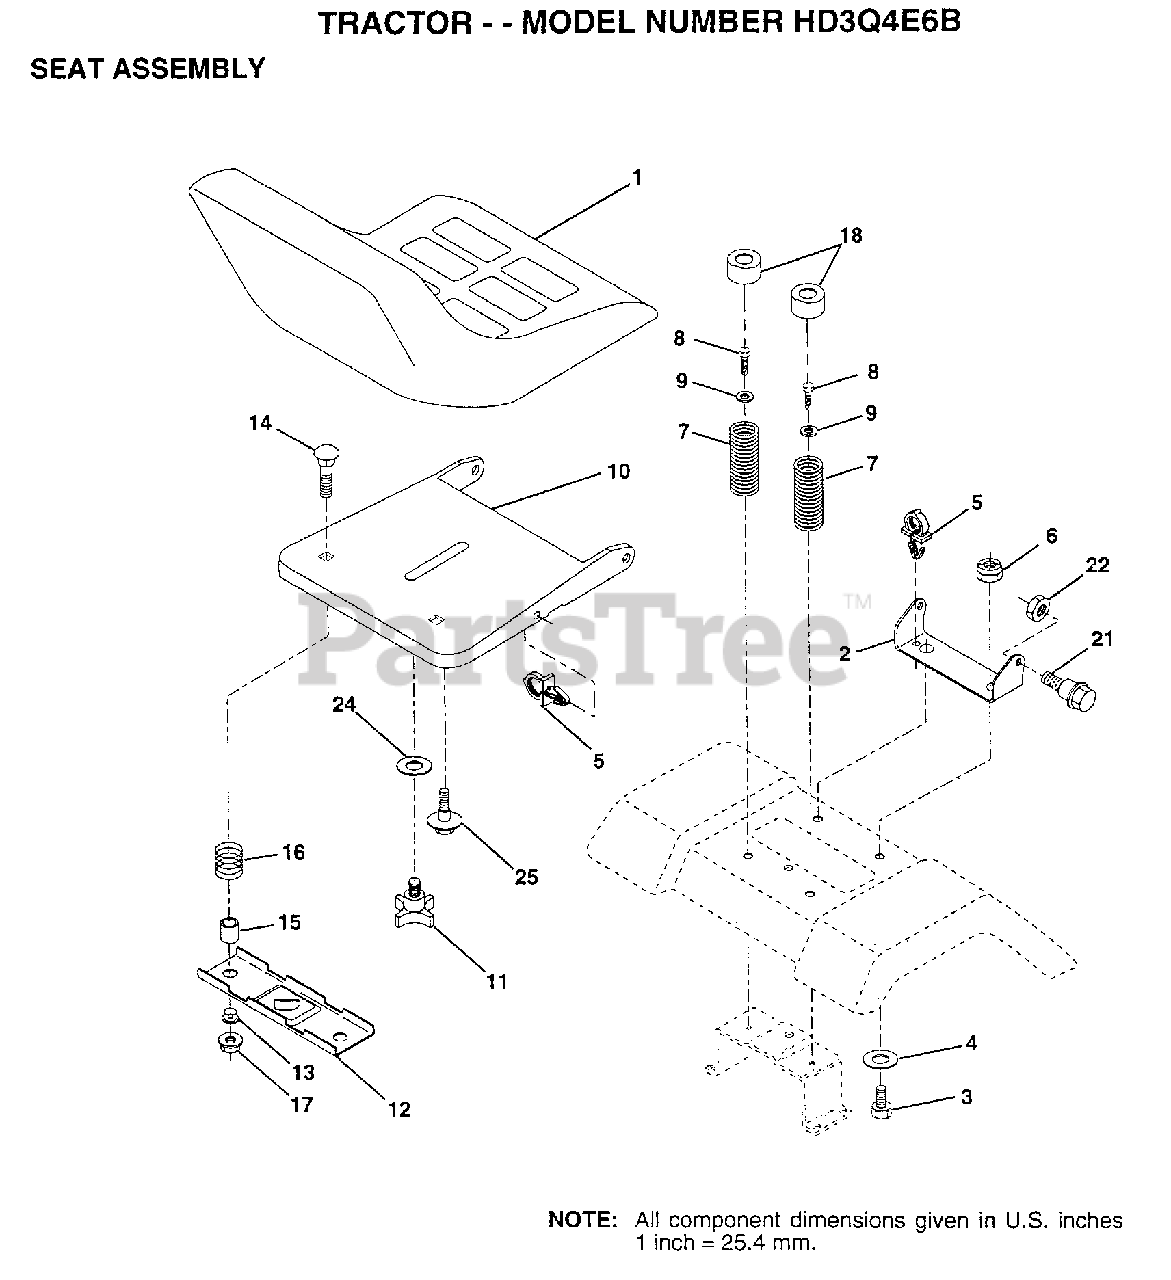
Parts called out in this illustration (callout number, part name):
1	SEAT.2500/1516.BK
2	BRACKET PVT SEAT
3	BOLT
4	WASHER PM
5	CLIP.PUSH-IN.HING
6	NUT
7	SPRING COMPRESSIO
8	SCREW GTV
9	WASHER
11	"KNOB 1/2"" YT"
12	BRKT SWITCH
13	BUSHING
15	SPACER SPLIT
16	SPRING COMPRESSED
18	CAP SPRING
21	"BOLT,SHOULDER"
22	NUT
24	WASHER
25	"BOLT,SHOULDER"
